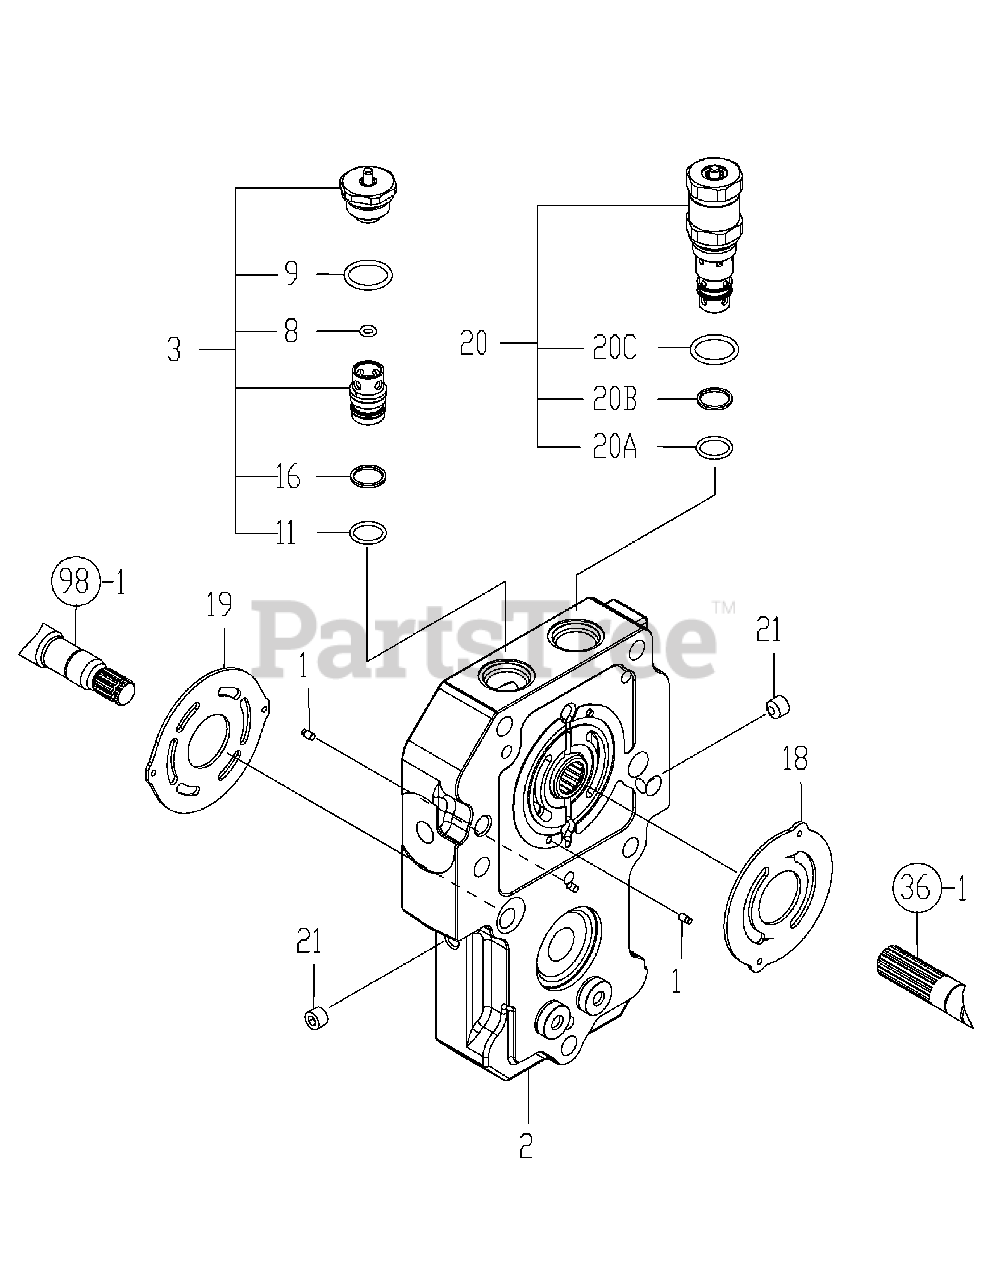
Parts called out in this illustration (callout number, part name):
1	PIN, KNOCK 3.5
2	CENTER CASE K93 CMP
3	CHECK VALVE (R CMP
8	PACKING, P 5.0
9	PACKING, P 20.0
16	RING, BACK UP 18
18	VALVE PLATE (P
19	VALVE PLATE (M
20	RELEAF ASSY,TOW 25
20B	RING, BACK UP 18
20C	PACKING, P 20.0
